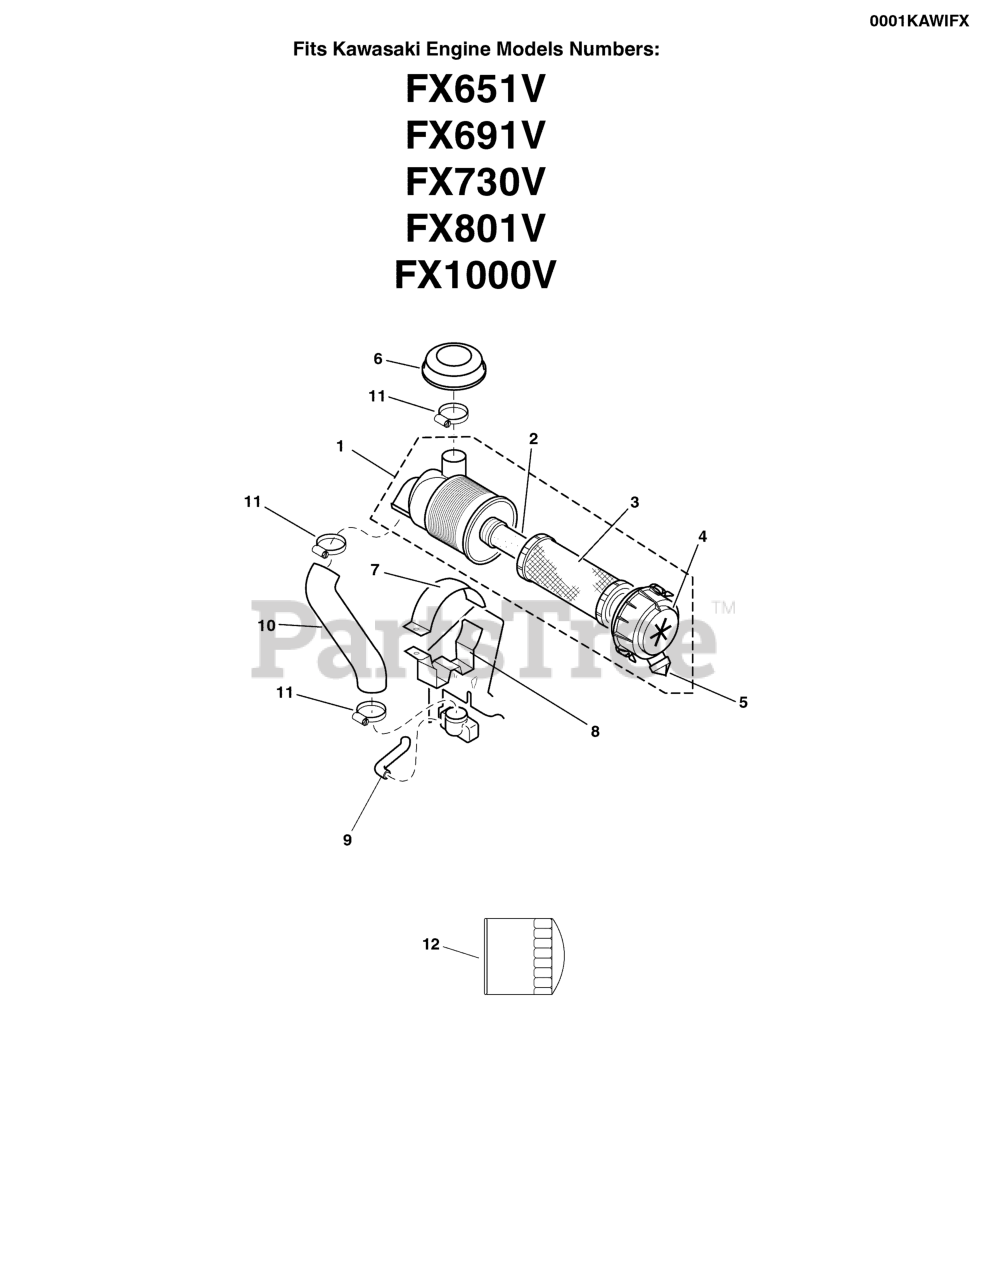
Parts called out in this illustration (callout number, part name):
1	AIR FILTER ASSEMBLY,22,24&26HP KAWASAKI
2	AIR FILTER,SECOND,FX651V THRU FX999 ENG
3	AIR FILTER,PRIMARY,FX 651,852, & 999 ENG
4	CASE, AIR FILTER, 22, 24 & 26HP KAWASAKI
5	DUST VALVE,AIR FILTR,22,24&26HP KAWASAKI
6	CAP, RAIN
7	BRKT,AIR FILTER,22,24&26HP KAV, OUTER
8	BRKT,AIR FILTER,22,24&26HP KAV, INNER
9	BREATHER TUBE, AIR FILTR,22,24&26HP KAWA
10	AIR INLET TUBE,AIR FILTR,22,24&26HP KAWA
11	CLAMP
12	FILTER,OIL,KAWA FS,FX651,700,FR 603 & 726CC ENG
12	FILTER,OIL,KAWA FX751,801,851,921,100
